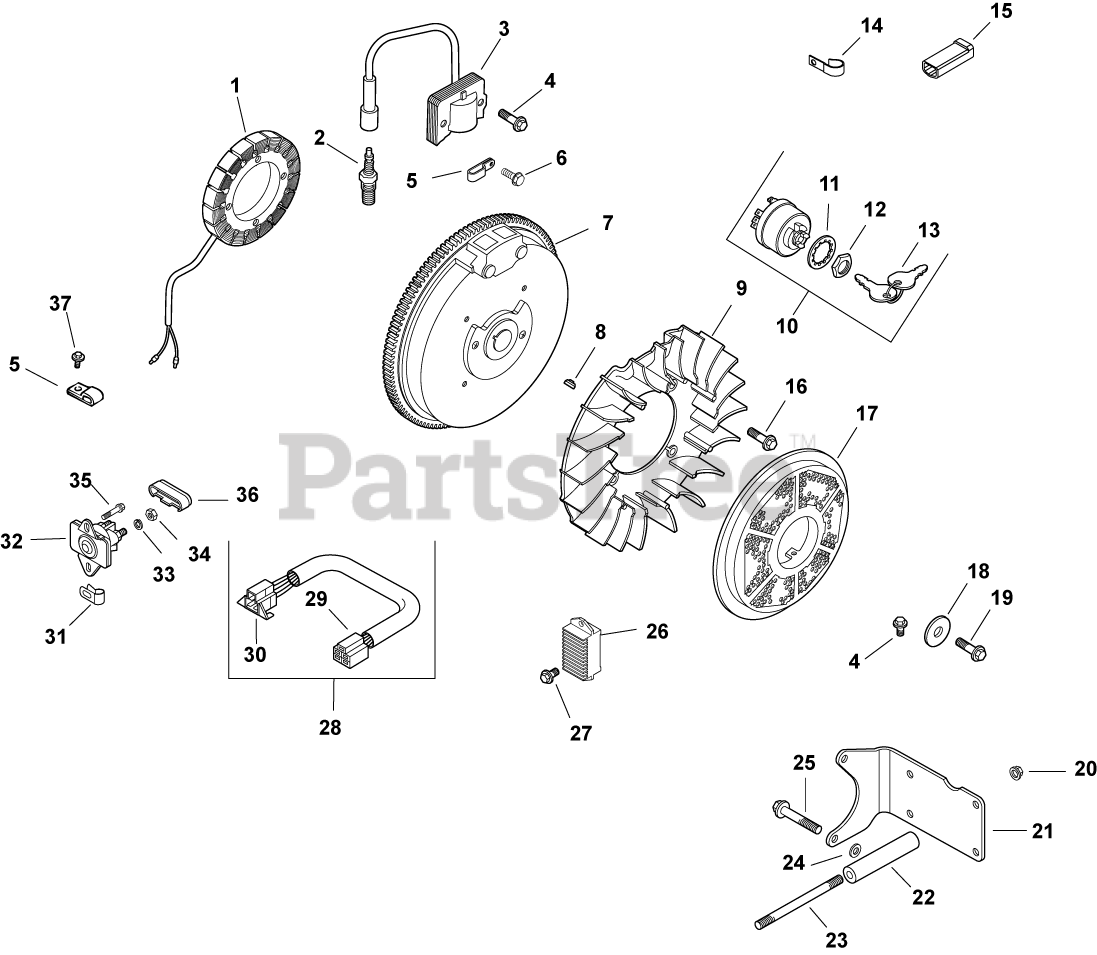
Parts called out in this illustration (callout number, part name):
1	KIT, 25 AMP STATOR ASSY.
2	PLUG, SPARK (STD)
3	MODULE, IGNITION
4	SCREW, FLG THD FRM M5X.8X20-(#25086399S)
6	SCREW, FLG THD FRM M5X.8X10
7	FLYWHEEL - USE 12 025 16-S
8	KEY, 3/16" X 5/8"
9	FAN - DISCONTINUED
10	SWITCH ASSY, KEY (KM)-USE 25 099 32-S
11	WASHER, INTERNAL TOOTH
12	NUT, KEY SWITCH
13	KEY, SET -USE 48 340 01-S
14	CLIP, CABLE
15	CONNECTOR (1 CONTACT)
16	BOLT, SHOULDER
18	WASHER, FLAT 13/32"
19	SCREW, FLG M10X1.5X45 - (#25086361S)
20	NUT, FLG M8X1.25
21	BRACKET, FUEL TANK
23	STUD, M8X1.25X133-USE 25 755 54-S
24	WASHER, FLAT 11/32"
25	SCREW, FLG M8X1.25X50
26	REG/RECTIFIER (20/25 AMP)-USE 25 403 20-
27	SCREW, FLG M6X1.0X16
28	CONNECTOR ASSEMBLY
29	CONNECTOR
30	CONNECTOR
32	SOLENOID - WATERPROOF (KM)-USE 25 435 08
33	WASHER, INT TOOTH LOCK 1/4"
34	NUT, JAM 1/4-20 GRADE 2
35	SCREW,FLG THD FRM M6X1.0X16-(#25086397S)
36	CAP, SOLENOID - DISCONTINUED
37	SCREW, THD FROM M5X0.8X30
